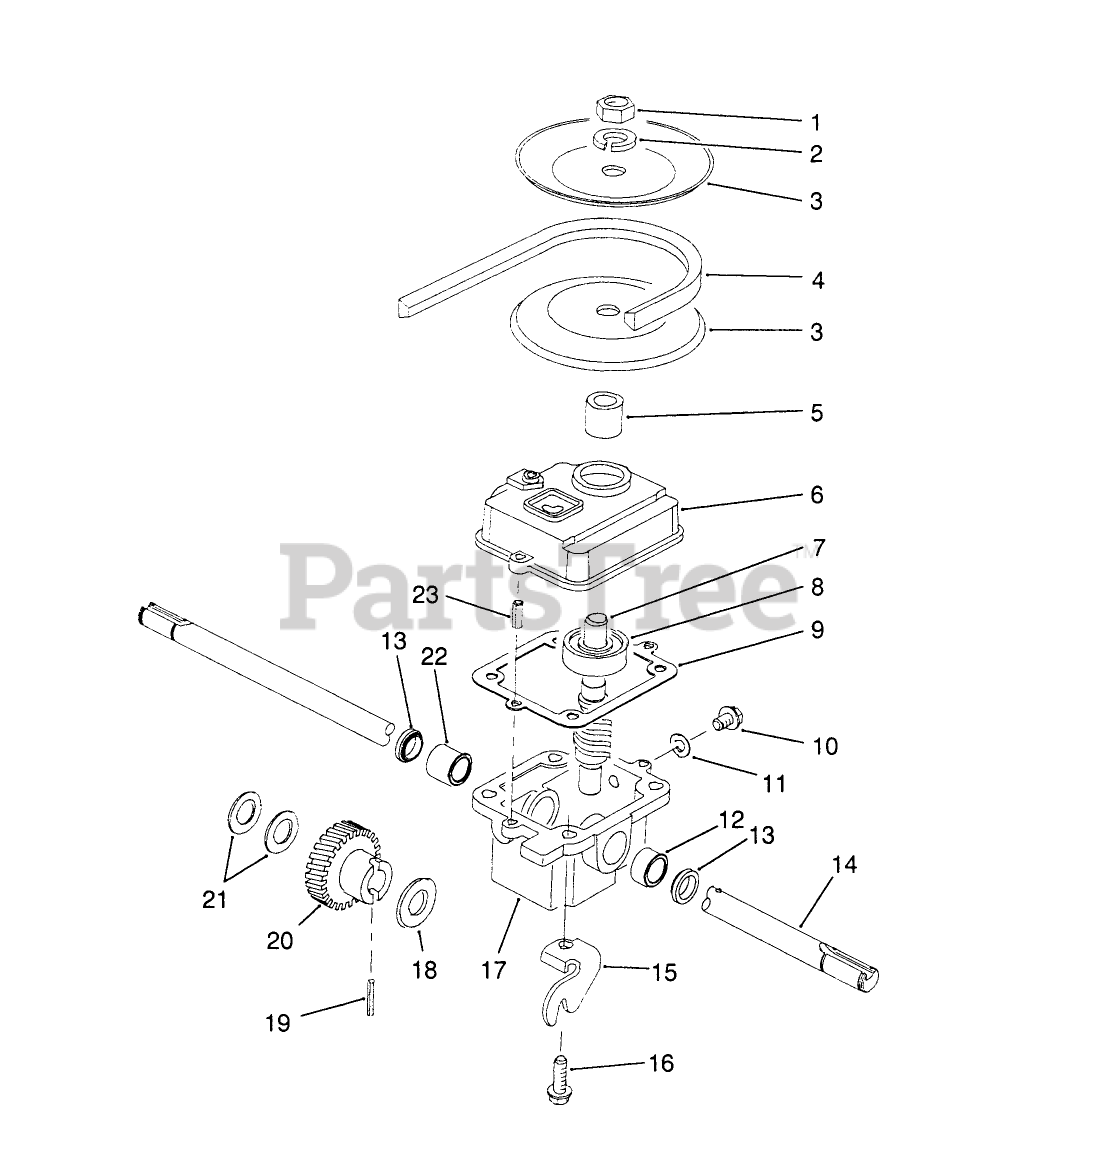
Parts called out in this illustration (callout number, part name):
1	NUT-JAM
2	WASHER-LOCK
3	PULLEY-DRIVEN HALF
4	V-BELT
5	SPACER - PULLEY
6	GEAR CASE COVER
7	SHAFT - WORM
8	BEARING
9	GASKET
10	NYLON SCREW
11	FILL PLUG GASKET
12	BUSHING
13	SEAL-OIL
14	OUTPUT SHAFT
15	TRACTION BRACKET
16	SCREW-HWHTF
17	GEAR CASE
18	THRUST WASHER
19	PIN-SPRING
20	GEAR - HELICAL
21	WASHER-PLAIN
22	BUSHING
23	3/16 X 1/2 ROLL PIN
